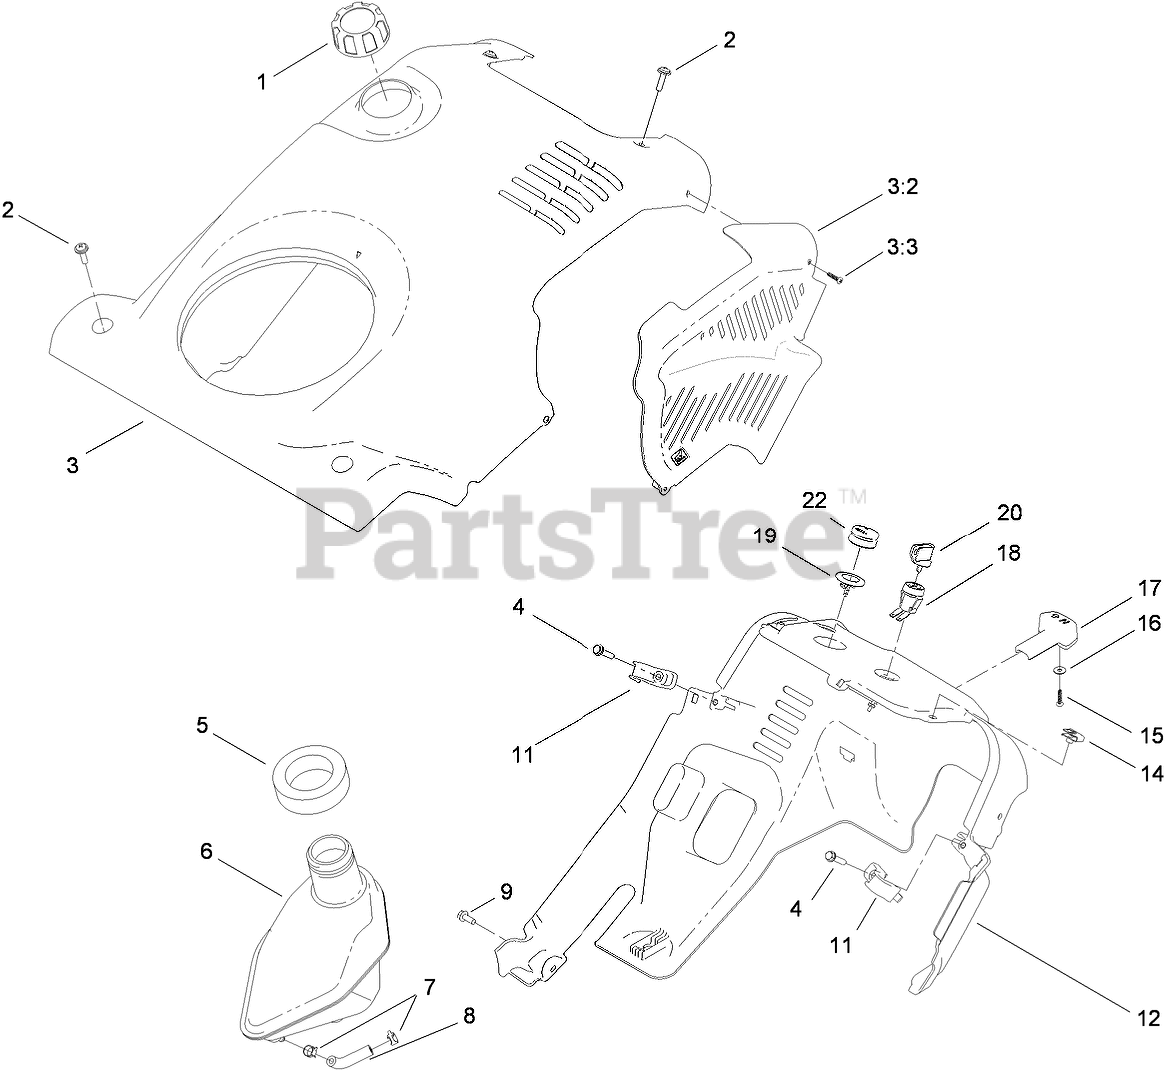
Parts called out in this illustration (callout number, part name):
1	4-CYCLE GAS CAP ASM
2	SCREW-PPH
3	SHROUD ASM
3:2	BAFFLE-EXHAUST
3:3	SCREW-PPH
4	SCREW-PLASTITE
5	SEAL-TANK
6	TANK-GAS
7	CLAMP-HOSE
8	HOSE-FUEL
9	SCREW-HWH
11	CLIP-SHROUD
12	SHROUD-LOWER
15	SCREW-PPH
16	WASHER-PLAIN
17	KNOB-CHOKE
18	SWITCH
19	BODY-PRIMER
20	KEY-IGNITION
22	BULB-PRIMER
